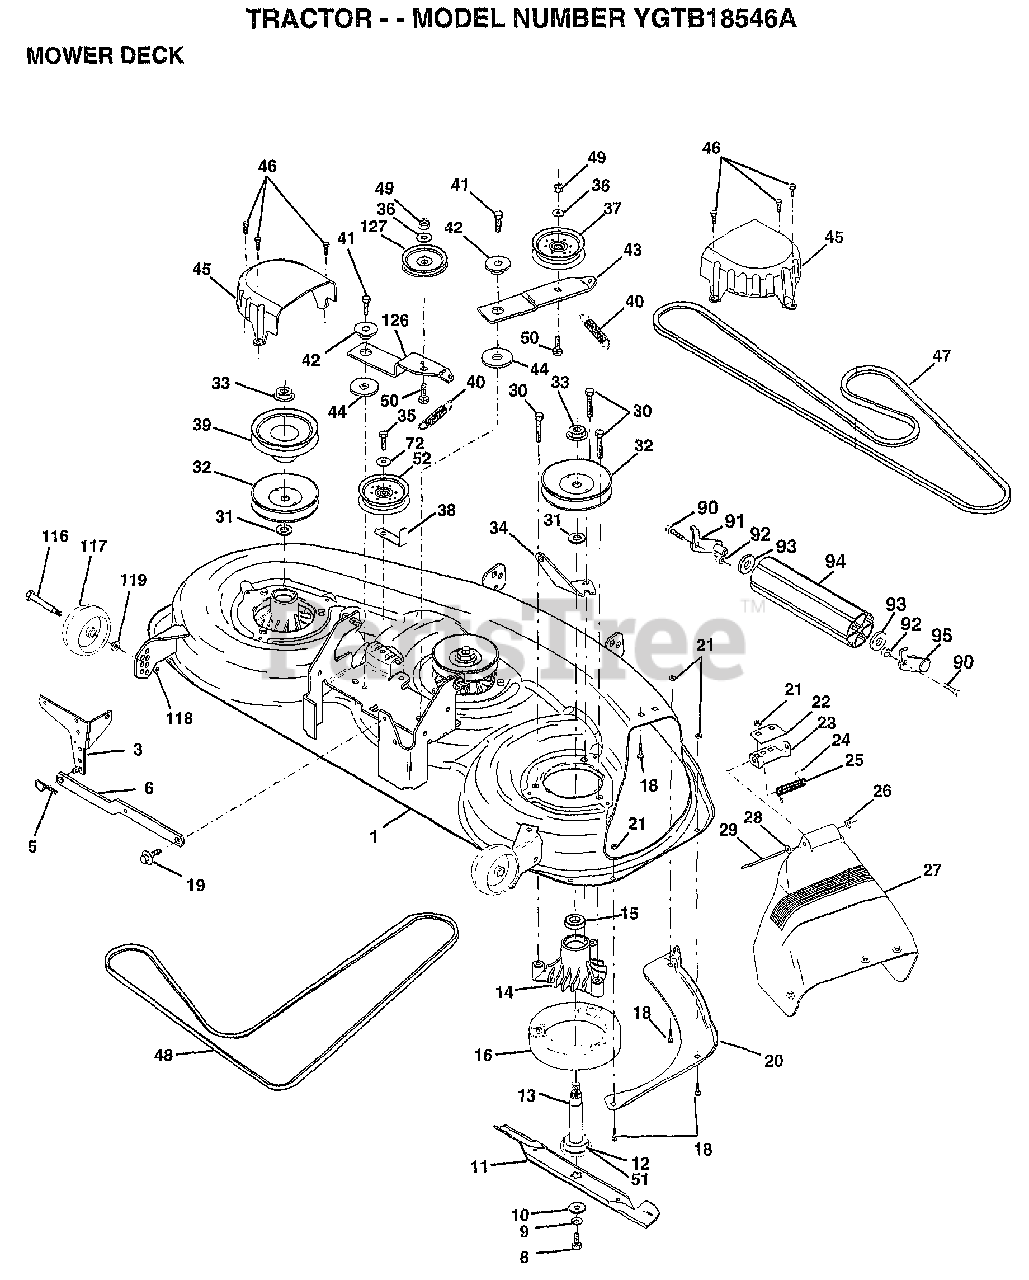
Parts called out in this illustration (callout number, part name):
1	"DECK.ASM.MOWER46"""
3	BRKT.ASM.SW.44/50
8	BLADE BOLT
10	WASHER.HARD.BLADE
11	"BLADE MULCH 46"""
12	BEARING.BALL
13	SHAFT.ASM.W/BRNG
14	HOUSING.MAND.44.V
15	BEARING
16	STRIPPER RND MWR
18	BOLT
19	BOLT SHD 5/16-18
20	BAFFFLE.VORTEX.46
22	STIFFENER BRKT
23	DEFLECTOR BRKT
24	CAP-SLEEVE LT
26	NUT PUSH M
27	SHIELD DEFLECTOR
28	WASHER
29	HINGE ROD
30	"SCREW-THD ROLL,WA"
31	WASHER
32	PULLEY.MAND.36/46
34	ANCHOR.SPRING.46
35	SCREW LT
36	WASHER
37	FLAT IDLER PULLEY
38	"KEEPER BELT,IDLER"
39	PULLEY.DRV.DCK.46
40	"SPRING.SEC.44""VEN"
41	SCREW
42	SPACER RETAINER
43	ARM.IDLER.DECK.46
44	HARDENED WASHER
45	COVER.MANDREL.46
46	SCREW.1/4-20X5/8
47	BELT-V.SEC.46.KEL
48	BELT.MWR.PRM.85.4
50	BOLT.3/8-16X1.50
51	WASHER.FELT.
52	"PULLEY IDLER,FLAT"
72	WASHER HYT
90	BOLT
92	NUT
93	WASHER
116	BOLT M
117	WHEEL.GUAGE
118	LOCKNUT
119	WASHER
126	ARM.IDLER.PRIM.46
127	PULLEY.IDLER.4.25
